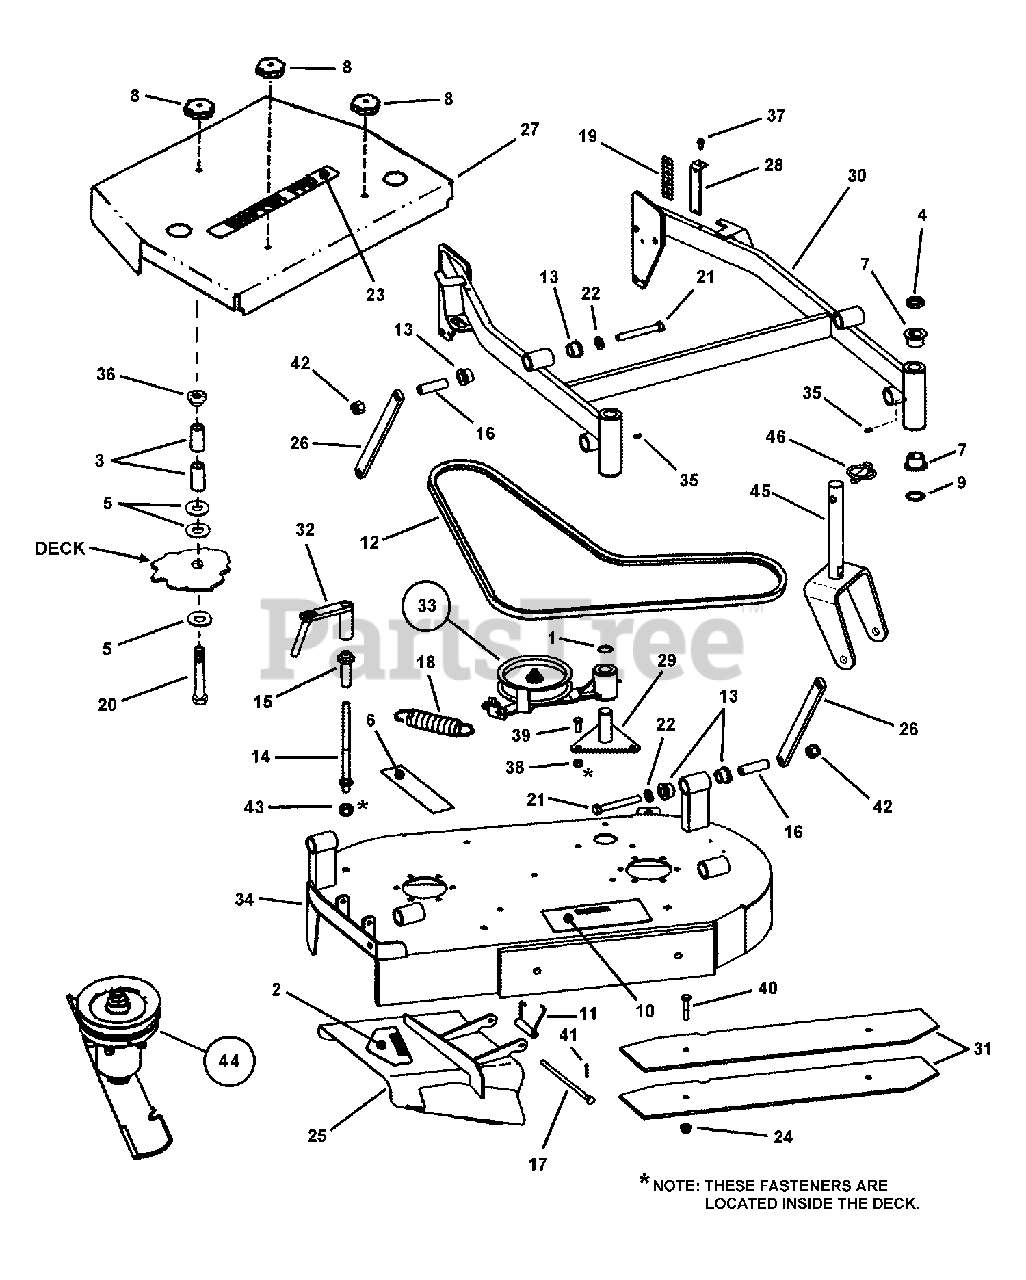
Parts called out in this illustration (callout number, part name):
1	RING, 1" External Retaining
2	DECAL, Warning (CPSC Cut Finger)
3	SPACER
4	SPACER, Powdered Metal
5	WASHER, 3/8" I.D. x 7/8" O.D. x 1/16" Flat
6	DECAL, Danger Guard/Catcher
7	BUSHING, Caster
8	KNOB, Hood (5/16-18 thread)
9	BUSHING, 1"
10	DECAL, Caution- Operator Instruction
11	SPRING, Chute
12	V-BELT, 36" Deck Drive (Nom. Effective Length: 84.80")
13	BUSHING, Suspension
14	STUD, Lift, 1/2-13 Thread, Both Ends
15	LIFT WASHER (Weldment)
16	SLEEVE, Suspension
17	HINGE PIN, Chute
18	SPRING, Idler
19	DECAL, Height of Cut
20	SCREW, 5/16-18 x 4-1/2" Hex Head Cap, GR 5
21	BOLT, 1/2-13 x 3-3/4" Hex Head, GR 5
22	WASHER, 1/2" Flat
23	DECAL, Snapper Pro (silver, 16-1/2" long)
24	NUT, 3/8-16 HEX SERRATED FLANGE
25	DEFLECTOR, 36" ANSI Compliant (Weldment)
26	ARM, Suspension, 12" Long
27	COVER, 36"
28	BRACKET, Height-of-Cut
29	PIVOT, Idler Arm (Weldment)
30	FRAME, 36" Adjustable (Weldment)
31	PLATE, Ballasat
32	ASSEMBLY, Crank
33	ASSEMBLY, Idler Arm, 36"
34	WELDMENT, Deck, Adjustable Height (Red)
35	GREASE FITTING, 3/16 Straight (press-in)
36	NUT, 5/16-18 Hex Flange Lock, GR 5
37	SCREW, 1/4-20 x 5/8" Hex Washer Self-Tap
38	NUT, 3/8-16 HEX NYLON LOCK
39	BOLT, 3/8-16 X 1" GD5 CZ
40	BOLT, 3/8-16 X 2, GD5, CZ
41	COTTER PIN, 3/32 x 1"
42	NUT, 1/2-13 HEX NYLON LOCK
43	NUT, 1/2-13 HEX SIDE LOCK
44	ASSEMBLY, Spindle
45	YOKE, Caster Weldment
46	LYNCH PIN, 7/16" Heavy Duty
